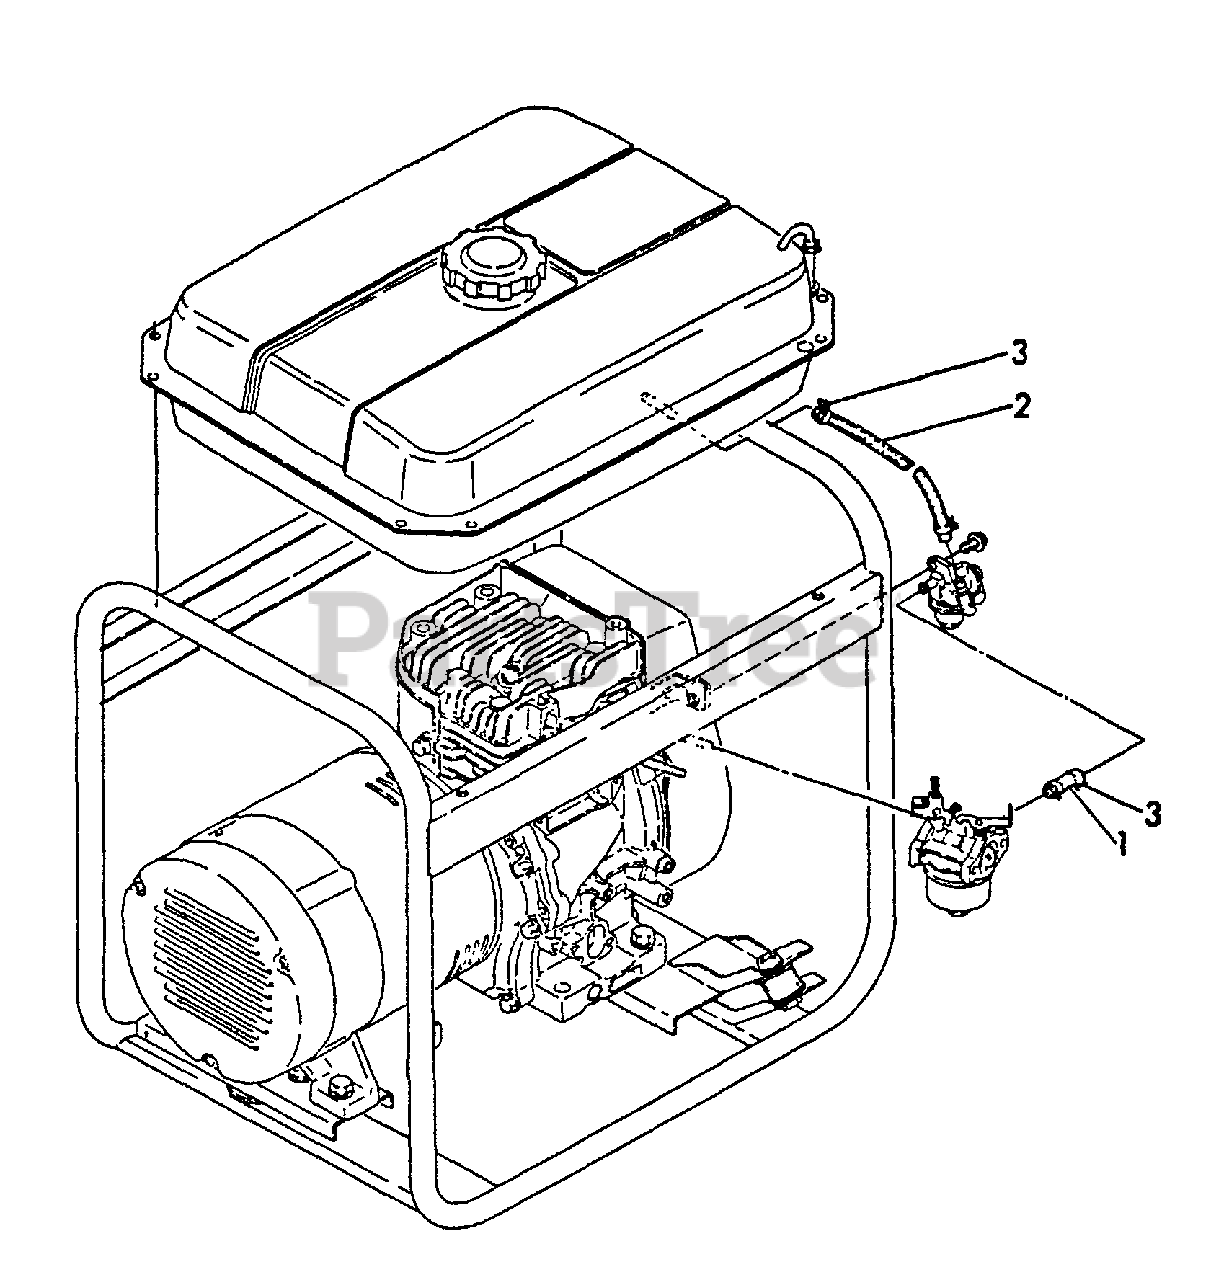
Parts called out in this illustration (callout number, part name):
1	PIPE, FUEL
2	PIPE, FUEL
3	CLAMP, HOSE - 10
